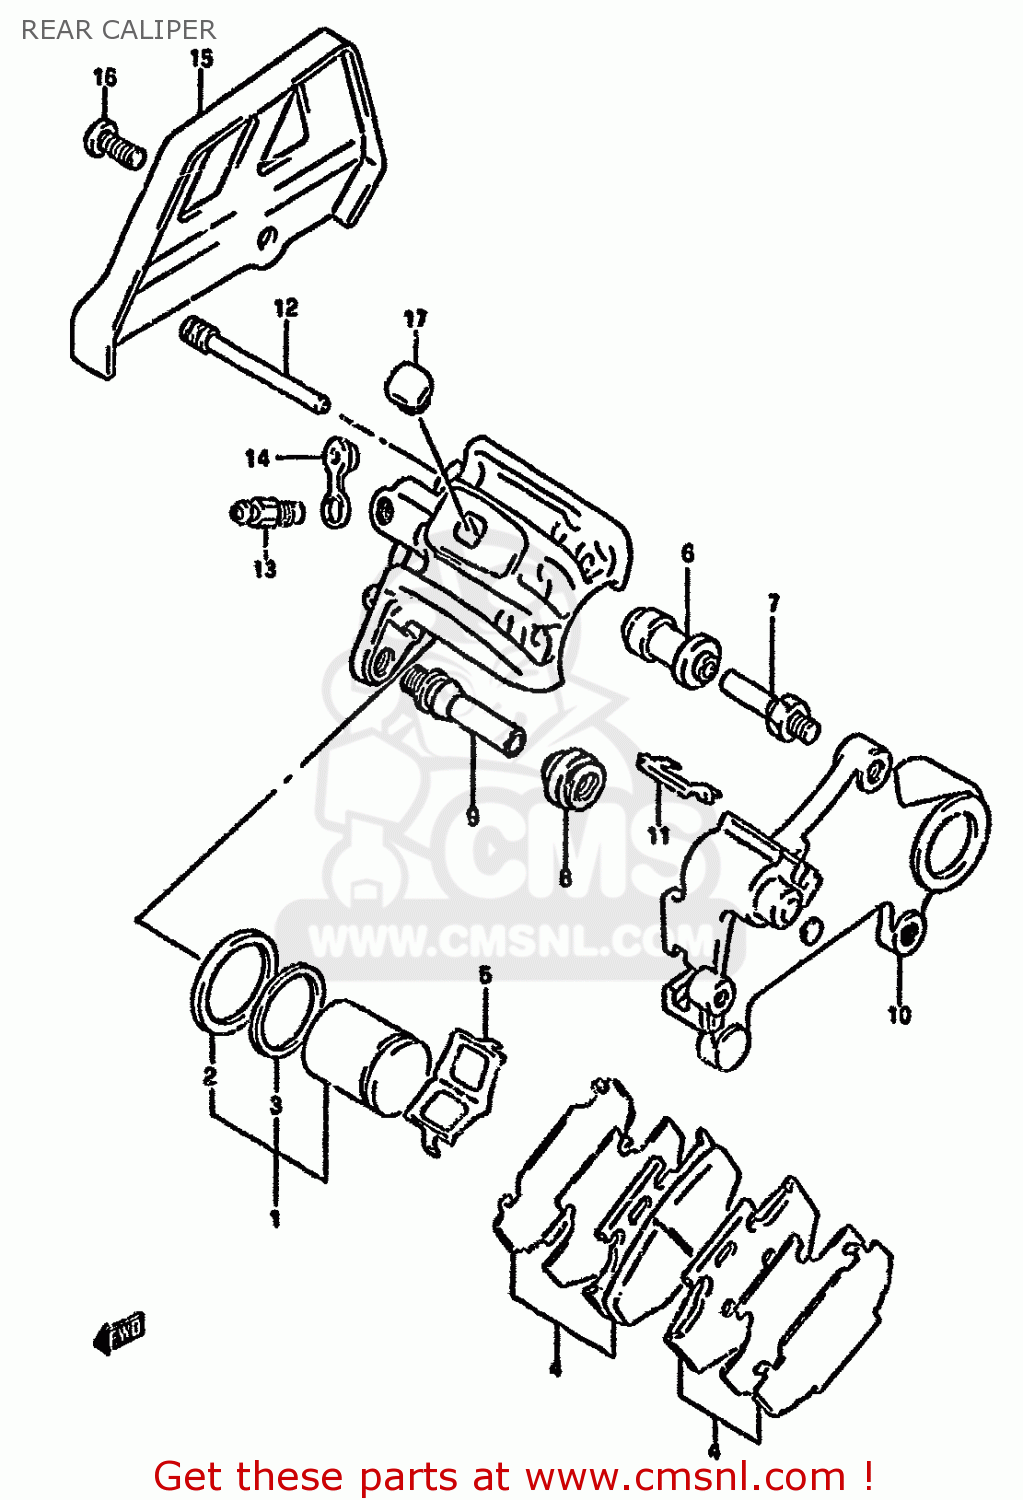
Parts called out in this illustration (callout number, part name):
1	PISTON SET
2	SEAL,PISTON
3	SEAL
4	PAD & SHIM SET (NAS)
5	SPRING,PAD
6	BOOT
7	PIN,BOLT
8	BOOT
9	PIN
10	BRACKET
11	RETAINER,BRACKET
12	PIN,HANGER
13	BLEEDER
14	CAP,BLEEDER
15	GUARD,REAR CALIPER
16	SCREW 6X12
17	COVER,RR CALIPER BODY
